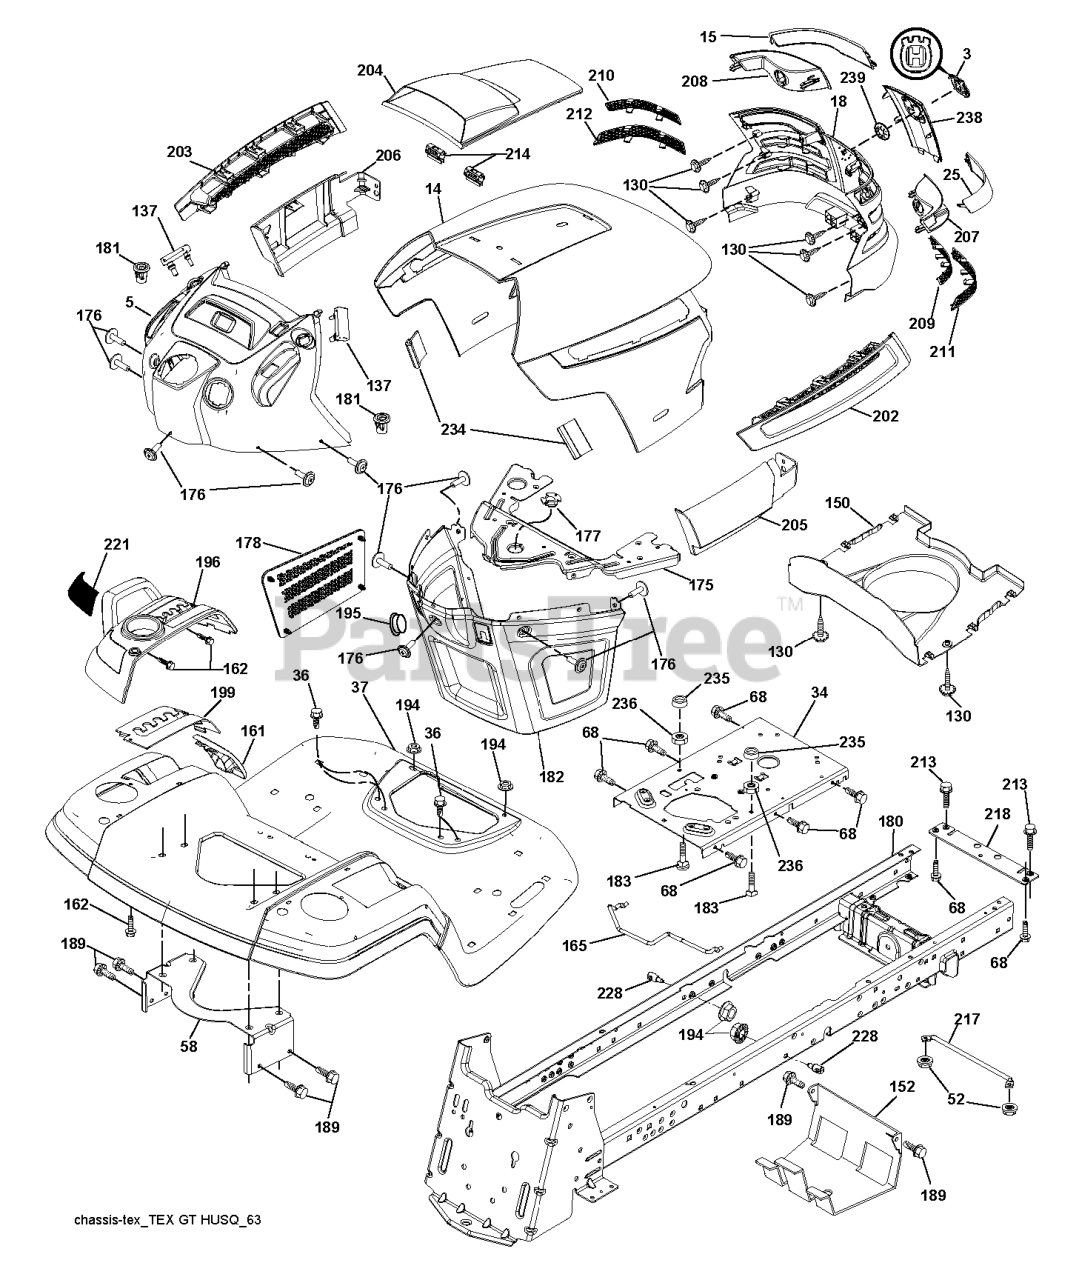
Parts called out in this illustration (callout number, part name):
3	RP LOGO
5	DASH.ASM.HUSQ.GT.E.RECT.W/CK
14	HOOD
15	LENS.LH.TEX.GT.HUSQ.CL
18	GRILL.ASM.HUSQ.TG/CRD.W/TRIM
25	LENS.RH.TEX.GT.HUSQ.CL
34	PLATE.ENGINE.WELDED.CHASSIS
36	SCREW 5/16"
37	FENDER.PNT.TX.GT.CH/FW.ORANGE
52	LOCKNUT
58	BRKT.SUPPORT.FNDR/TANK
68	Screw 5/16-18 x 1/2 Hex, Self Tapping 5/16-18 x 1/2
130	SCREW.#10 X 0.750.BOS
137	BUMPER DASH
150	AIR.DUCT.HOOD.TEX.GT.HUSQ
152	SHIELD.BROWNING.W/TEX
161	CONSOLE.FUEL.WINDOW.HU
162	SCREW.HI-LO.CONSOLE
165	SUPPORT.TANK.REAR.W/TEX
175	PLATE.CROSSMEMBER.HUSQ
176	SCREW.#10-24X5/8.RN.QU
177	BUSHING, STEERING
178	CARGO.ASM.NET.TXGT.W/C
180	CHASSIS.GT.SLOPED.DRAWBAR.
181	BUSHING.MNT.FEND.CRGO.
182	DASH.LOWER.COMMON.12V.ADAPTOR
183	BOLT.5/16-18X1-1/4 FULL.THREAD
189	SCREW
194	NUT LOCK HEX FLANGE 5/16-18
195	PLUG.HOLE.DASH.LOWER.12V.BLK
196	RP CONSOLE.ASM.DECKLFT.W/
199	PLATE.DECK.LIFT.HUSQVARNA.GT
202	VENT.SIDE.HOOD.HUSQ.RH.GREY
203	VENT.SIDE.HOOD.HUSQ.LH.GRAY
204	HOOD VENT
205	SKIRT.HOOD.SIDE.HUSQ.RH.GREY
206	SKIRT.HOOD.SIDE.HUSQ.LH.GREY
207	BEZEL.RH.TEX.GT.HUSQ
208	BEZEL.LH.TEX.GT.HUSQ
209	INSERT.HEX.GRILL.HUSQ.GREY
210	INSERT.HEX.GRILL.HUSQ.
211	INSERT.HEX.GRILL.HUSQ.
212	INSERT.HEX.GRILL.HUSQ.
213	BOLT
214	CLIP.RETAINER.TINNER.
217	ROD.PIVOT.HOOD
218	X-PIECE.HOOD.STOP.NON/
221	REFLECTOR.LH.TEX GT HU
228	STUD.FASTNER.W/ANTI-ROTATE
234	BUMPER.HOOD.TEX.HUSQVARNA
235	SPACER FENDER
236	NUT.CENTERLOCK.5/16-
238	TRIM.HUSQ.TG/CRD.SERVICE
239	NUT PUSH M
